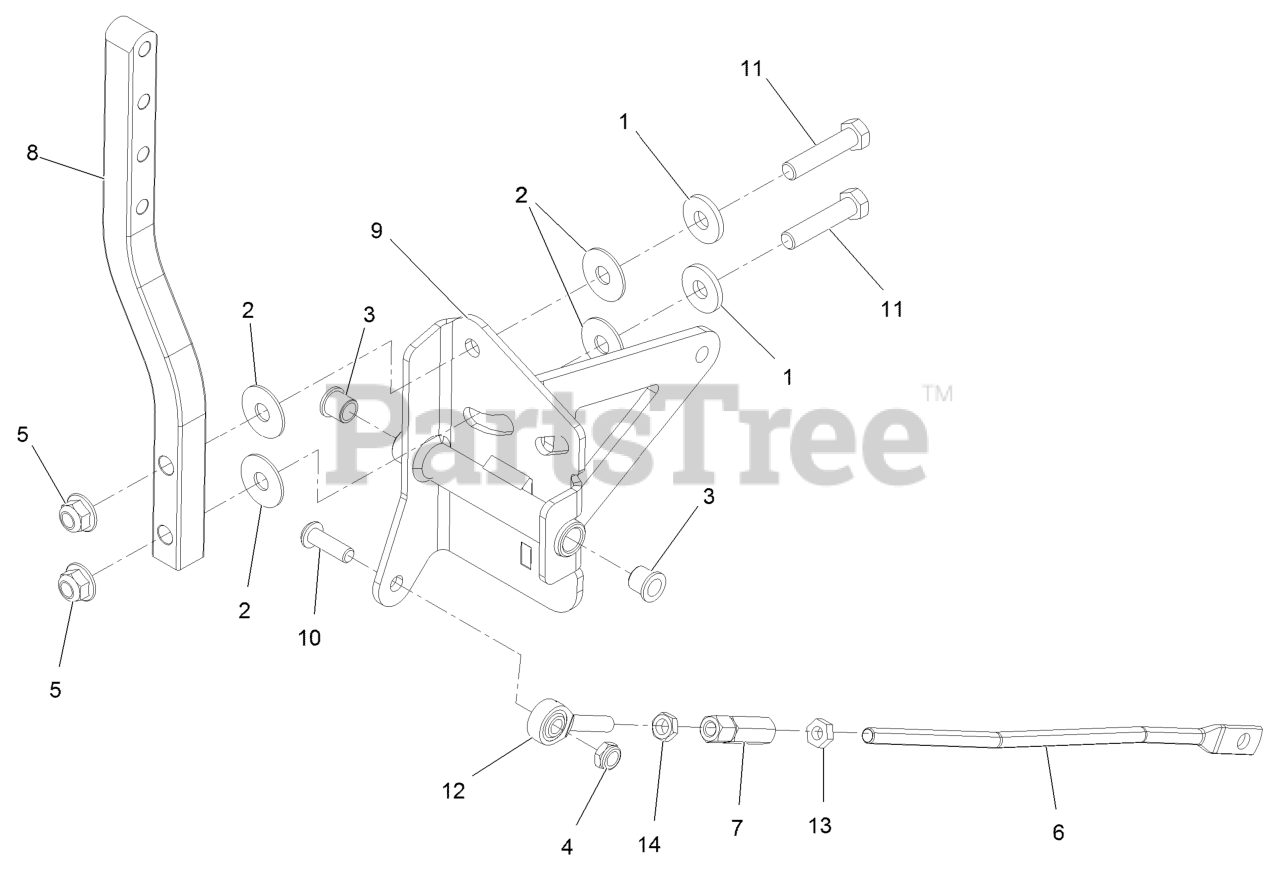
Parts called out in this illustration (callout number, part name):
1	WASHER
2	WASHER-PLASTIC
3	BEARING
4	NUT-LOCK, NI
5	NUT-HF, NI
6	LINK,MOTION CONTROL
7	NUT-ROD ADJUSTMENT
8	ARM-MOTION CONTROL
9	RH CONTROL PIVOT ASM
10	SCREW-HSBH
11	SCREW-HH
12	BEARING-ROD END, LH
13	NUT-JAM
14	NUT-JAM
